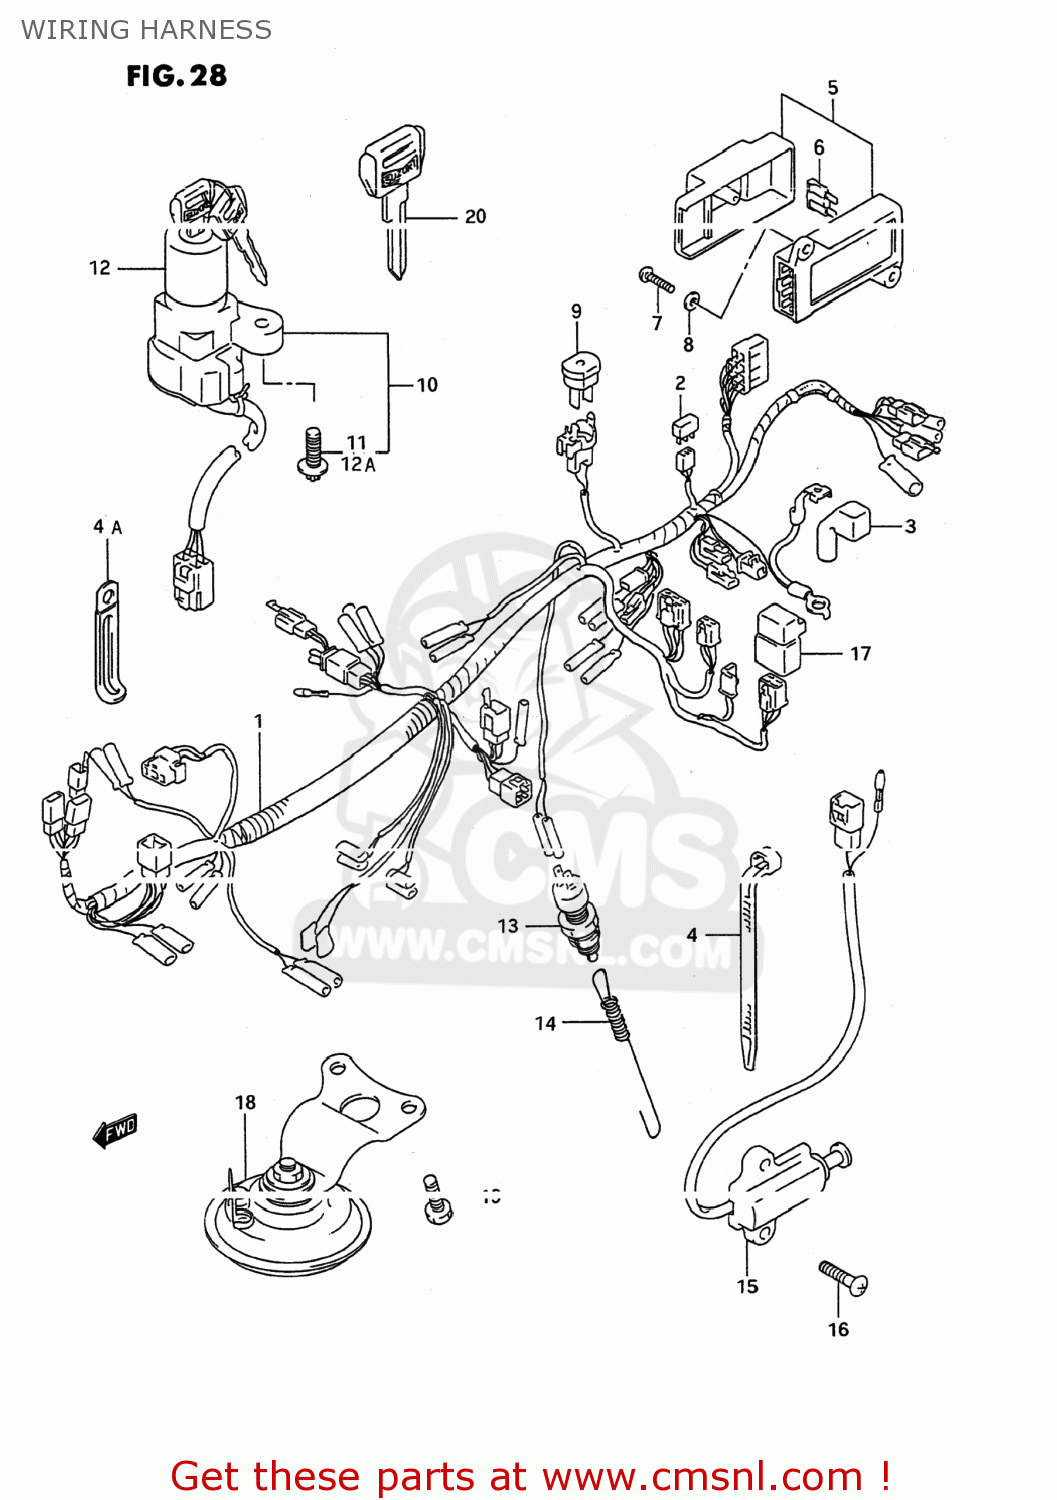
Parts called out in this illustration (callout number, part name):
1	HARNESS,WIRING
2	DIODE(STANLEY DE8804)
3	CAP,BATTERY PLUS
4	CLAMP(L:95)
4A	CLAMP
5	BOX ASSY,FUSE
6	FUSE(10A)
7	SCREW
8	WASHER
9	BREAKER ASSY,CIRCUT
10	LOCK ASSEMBLY,STEERING
11	SCREW(6X18)
12	LOCK ASSEMBLY,STEERING
12A	SCREW(6X18)
13	SWITCH ASSY,STOP LAMP
14	SPRING
15	SWITCH ASSEMBLY,SIDE STAND
16	BOLT
17	RELAY ASSY
18	HORN ASSY
19	BOLT
20	KEY,BLANK
